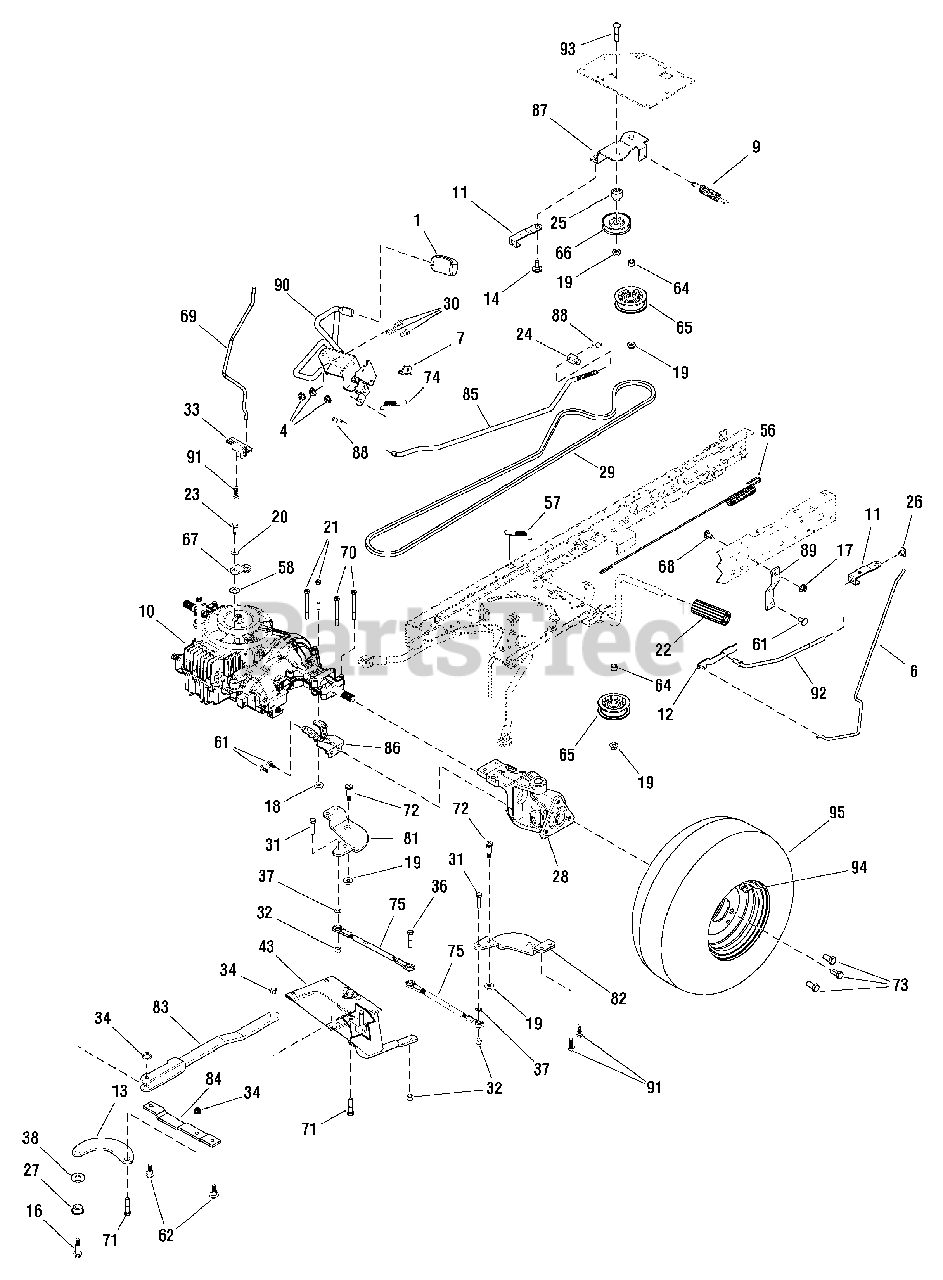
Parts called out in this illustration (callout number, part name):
1	PAD, Foot Pedal
4	NUT, Hex Flange, 5/16-18
6	ROD, Parking Brake
7	GEAR, Cruise
8	WHEEL ASSEMBLY
9	SPRING, Clutch
10	TRANSAXLE, PGM 2000 LTH - RH*
11	LINK, Clutch
12	LATCH, Parking Brake
13	CAM, Follower
14	BOLT, Shoulder, 3/8-16 x 1/2
16	BOLT, Shoulder, 3/8-24 x 1-7/8
17	NUT, Hex Flange, 3/8-16
18	NUT, Hex Flange, 5/16-18
19	NUT, Flange Lock, 3/8-16
20	WASHER, Flat, 3/4
21	BOLT, Hex, 5/16-18 x 3-3/8
22	PEDAL, Clutch and Brake
23	CAPSCREW, 1/4-28
24	NUT, Adjusting
25	BUSHING, Pivot
26	NUT, TEE
27	BUSHING, CAM
28	REAR STEER ASSEMBLY
29	V-BELT, 4L, 88.96 EL
30	BOLT, Carriage, 5/16-18 x 5/8
31	BOLT, Hex, 3/8-24 x 1-1/2
32	NUT, Hex, 3/8-24
33	BRACKET, Disconnect
34	NUT, Centerlock, 3/8-24
36	CAPSCREW, Hex Head, 3/8-24 x 3/4
37	WASHER, Spring Lock
38	WASHER, Flat 1-1/4
43	REAR PIVOT SHAFT ASSEMBLY
56	SPRING, Brake
57	SPRING, Extension
58	WASHER, Flat 1
61	SCREW, Thread Forming, 5/16-16 x 3/4
62	CAPSCREW, 5/16-18 x 3/4
64	SPACER, 1/2 to 17mm
65	PULLEY, Idler, 2-3/4 in
66	PULLEY, Idler, 3 in
67	ARM, Disconnect
68	BOLT, Carriage, 3/8-16 x 3/4
69	ROD, Roll Release
70	BOLT, Shoulder, 5/16-18 x 3
71	BOLT, Shoulder, 3/8-24 x 1-1/4
72	BOLT, Shoulder, 3/8-16 x 7/8
73	SCREW, 5/16-18 X 1-1/4
74	SPRING, Extension
75	TIE ROD ASSEMBLY
81	ARM, Rear Wheel Steer, Right
82	ARM, Rear Wheel Steer, Left
83	DRAG LINK
84	BRACKET, CAM Follower Mount
85	CONTROL ROD
86	BRACKET, Transaxle Support
87	IDLER ARM ASSEMBLY
88	HAIR PIN
89	STRAP, Torque
90	FOOT CONTROL
91	SCREW, 3/8-16 x 1
92	ROD, Clutch
93	BOLT, Carriage, 3/8-16 x 2
94	VALVE STEM, TR412
95	TIRE, 20 x 8-8, 2 Ply
